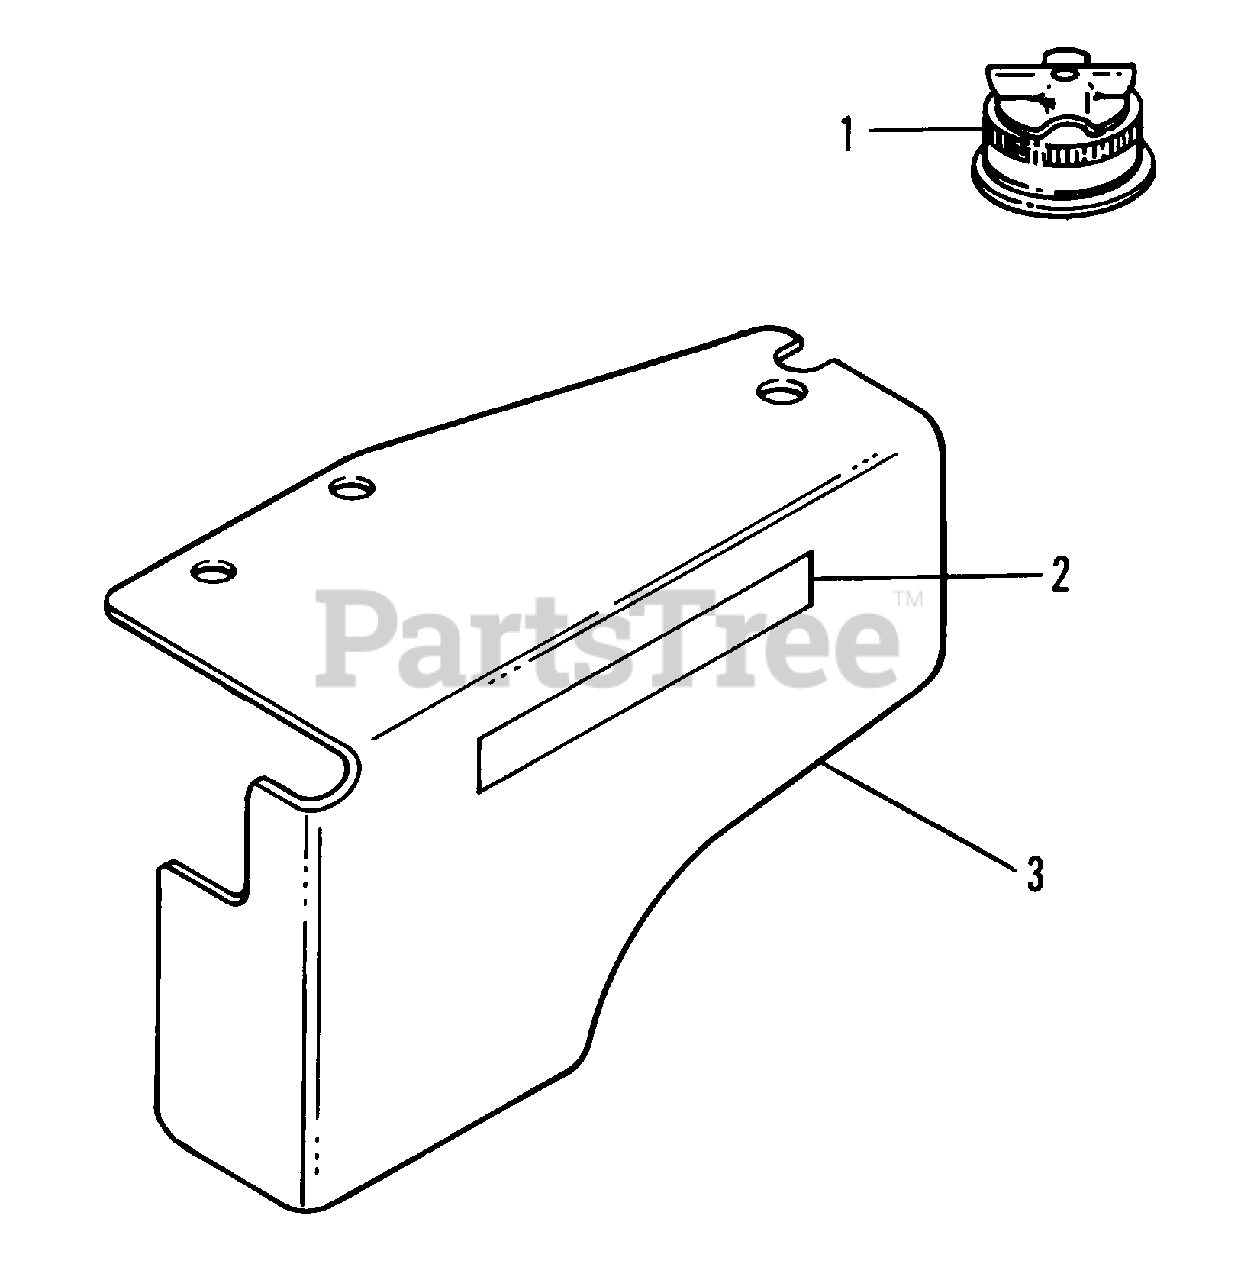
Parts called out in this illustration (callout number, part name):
1	CAP, Winterized
2	FILM, Shield
3	DEFLECTOR, Heat
